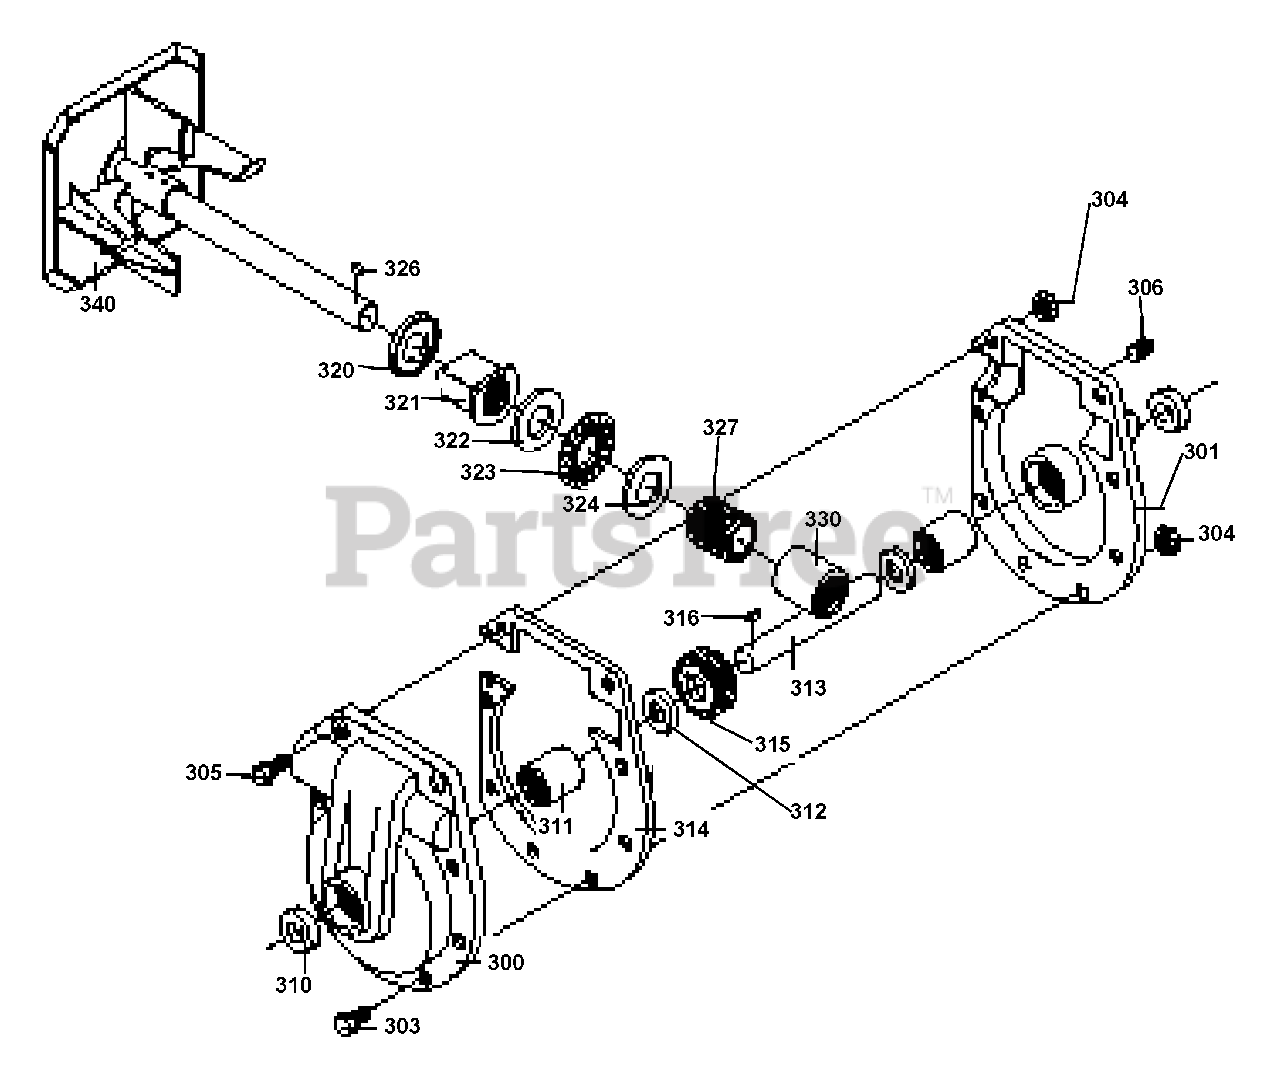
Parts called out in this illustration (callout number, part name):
300	CASE, GEAR RH
301	CASE, GEAR LH
303	SCREW, 5/16-24X1.00
304	NUT, 5/16-24
305	SCREW, 5/16-24X1.50
311	BEARING, SLEEVE
312	WASHER, FLAT
313	SHAFT, AUGER OUTPUT
314	GASKET, GEAR BOX
320	RING, QUAD
322	FLATWASHER
323	BEARING, ROLL
324	FLATWASHER 75X124X.093PL
326	KEY, HI-PRO
330	BEARING, SLEEVE
340	IMPEL, ASSY
